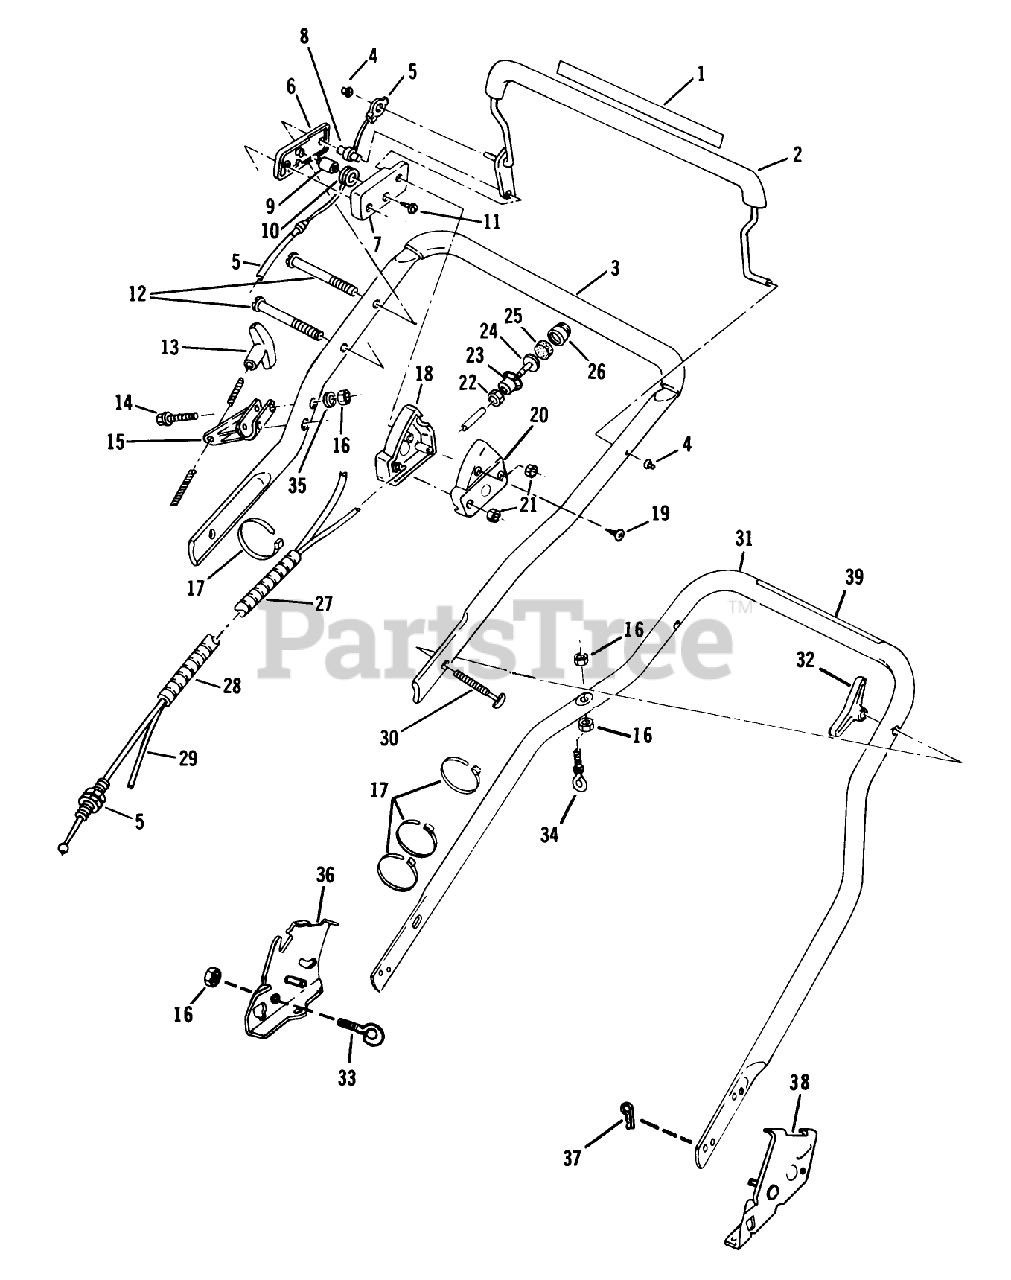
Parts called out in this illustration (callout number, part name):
5	CONTROL CABLE WES
8	COLUMN
9	PIN SKF
11	SCREW
13	HANDLE,STARTER
16	LOCKNUT E
19	SCREW LAWRENCE
21	NUT C/LOCK E
22	LOCKNUT S
25	FILTER S
30	BOLT QUALITY
32	NUT-WING
34	EYE BOLT WAS MFG
35	WASHER
37	HAIR PIN
